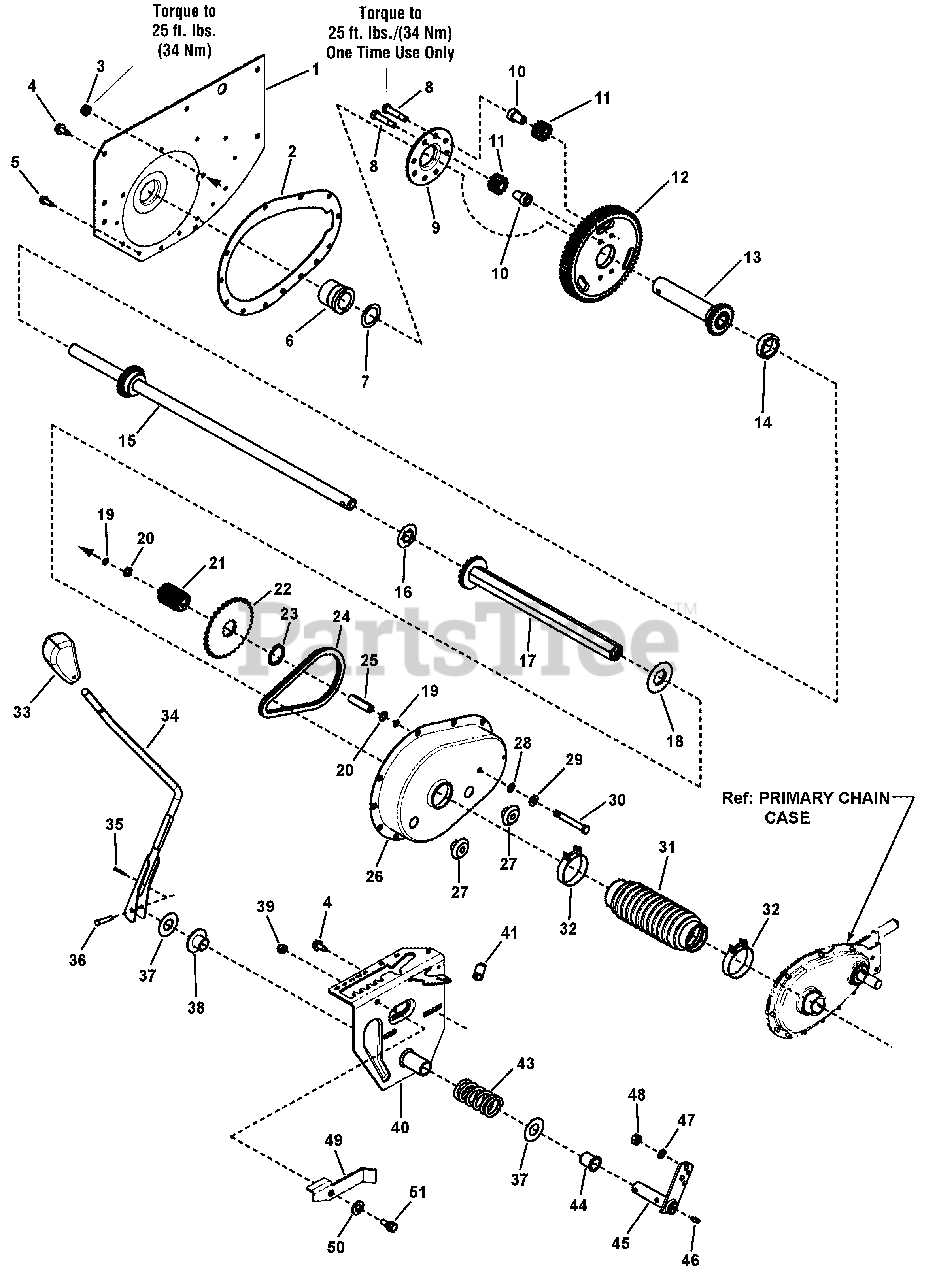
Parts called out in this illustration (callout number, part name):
1	FENDER, RH, 1.615 Hole, RER
2	GASKET, Transmission Case
3	NUT, 5/16-24, Serated Flange, Zinc/Clear, GR5
4	SCREW, 5/16-18 X .625, Hex Washer Head, Thread Roll, Zinc/Clear
5	SCREW, Hex Washer Head, 1/4-20 x 5/8
6	BEARING, Axle, 1.126 ID, 1.626 OD, PM
7	WASHER, Thrust (1.37 ID, 1.625 OD)
8	BOLT, 5/16-24 x 1-5/8 Hex Nylock, G5, Black
9	PLATE, Differential, Heat Treated (8 holes)
10	SPACER, Pinion
11	GEAR, Differential Pinion (12T, 12P)
12	GEAR, 63 Tooth 10 Pitch (4 Hole)
13	ASSEMBLY, Short Axle, 23T
14	SPACER, Differential (1.25 ID x .425 Wide)
15	KIT, 23 Tooth Long Axle & Spacer (Includes 7047763 Axle & Spacer 7074431)
16	WASHER, Thrust, (Hex Flanged)
17	ASSEMBLY, Drive Hex Tube 13.2 Long
18	WASHER, Nylon
19	O-RING, 5/16"
20	WASHER, 5/16 X 5/8 X .05, Belleville
21	GEAR, 11 Tooth, 10 Pitch, PM
22	SPROCKET, 34T, 3/8P
23	RING, 1-3/16 External Retaining
24	CHAIN, 46 Pitch (#35 Endless)
25	SPACER, .50 OD X .031 ID X 1.75 Long, Heat Treated
26	CASE, Transmission
27	PLUG, 3/4"
28	WASHER, External Tooth, 5/16
29	WASHER, 5/16, Flat SAE, Zinc/Clear
30	SCREW, 5/16-24 x 2-5/8 Hex Head Cap, ZP
31	BOOT, Rear Axle
32	CLAMP, 2 ID
33	GRIP, Shift Handle
34	WELDMENT, Shift Handle
35	PIN, 3/32 X 3/4, GR5, Cotter, Zinc/Clear
36	PIN, .25 X 1.25, Clevis
37	WASHER, Thrust .76 ID, 1.62 OD, .025 Thick
38	BUSHING, 3/4 ID, 1.62 Flange (Nylon)
39	NUT, 5/16-18, Hex Nylock, Zinc/Clear
40	SPEED ADJUSTMENT LATCH ASSY.
43	SPRING, Shift Detent
44	BUSHING, 3/4 ID, 1 Flange (Nylon)
45	WELDMENT, Shift Arm
46	FITTING, Lube (Straight press fit for .187 hole, n
47	WASHER, .32 X .58 X .08, Split Lock, YZ
48	NUT, 5/16-24, Hex, GR5, Zinc/Clear
49	LEVER, Over-Ride
50	WASHER, .922 X .065 X .065, Flat, Zinc/Clear
51	BOLT, 5/16-18 X .750, Hex Washer Head Shoulder, Zinc/Clear
54	KIT, Long & Short Axle (Includes items 13, 14, & 15)
